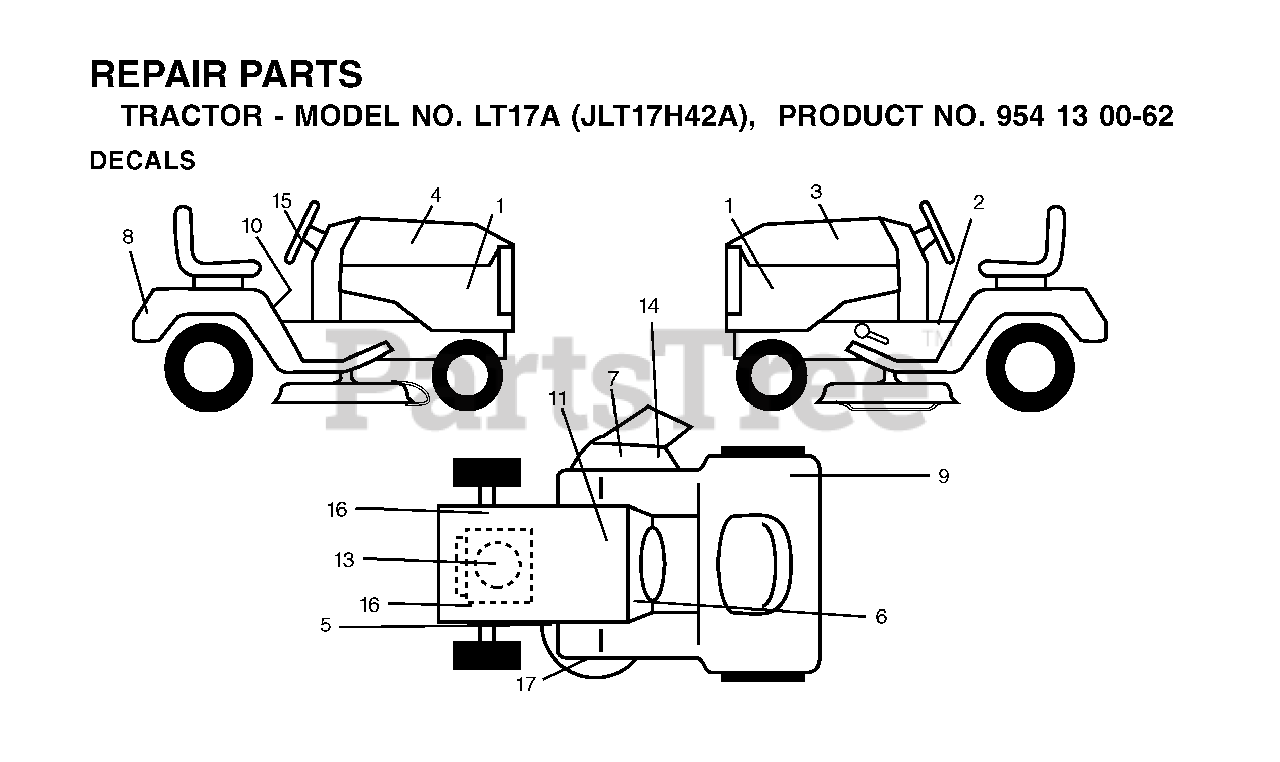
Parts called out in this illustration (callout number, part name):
2	DECAL PARK BRAKE
3	HOOD DECAL LH
5	DECAL V BELT SCHEMATIC
7	DECAL.INTERNATIONL.CUTFINGER
10	DECAL READ OWNER'S MAN SYMS
11	DECAL BTRY SYMBOLS
14	DECAL DECK "B" 42"
